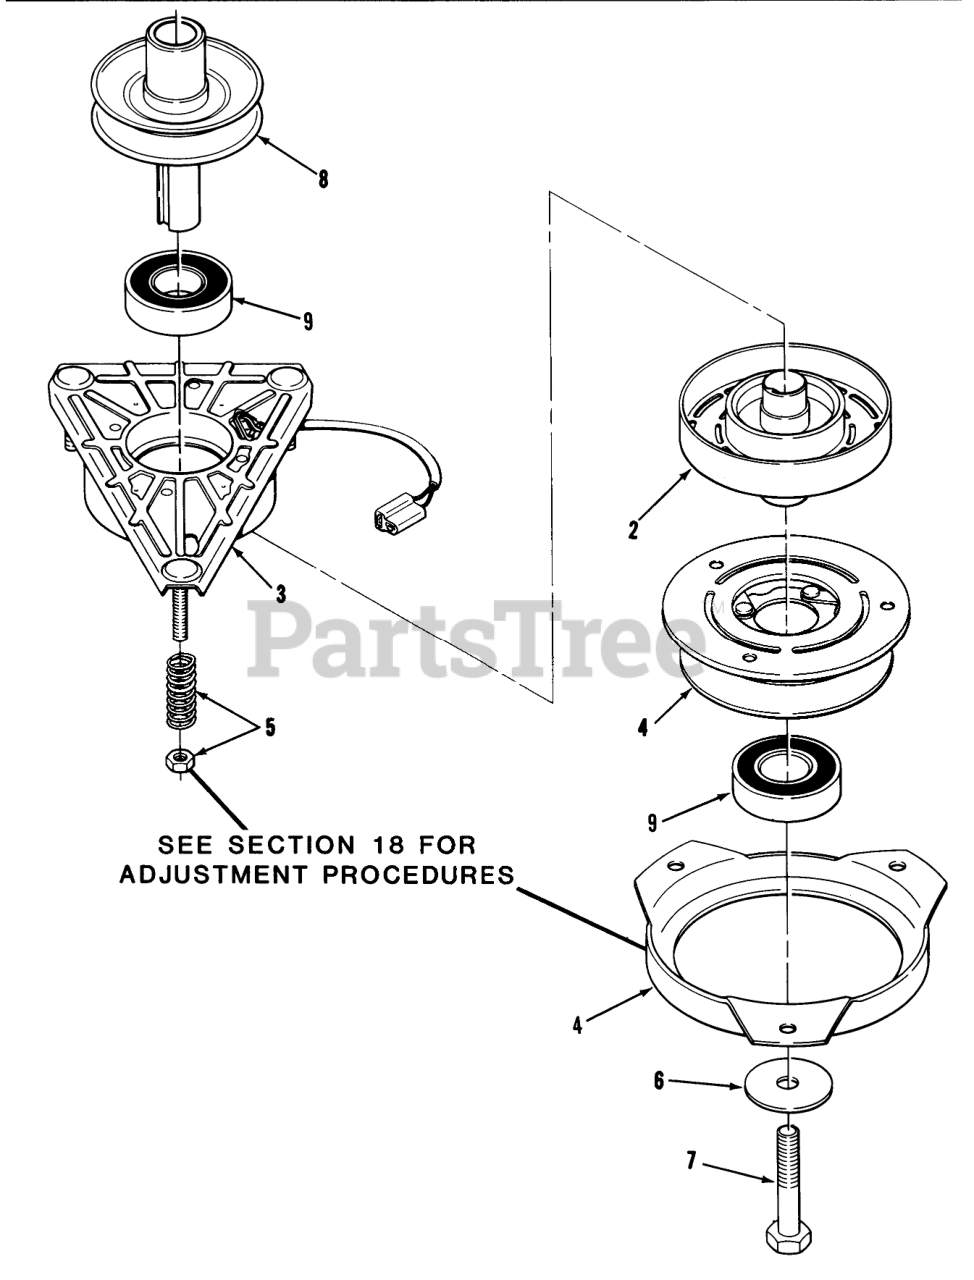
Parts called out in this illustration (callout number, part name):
1	Electric Clutch Assy (Includes items 2,3,4, & 5)
2	ASS'Y-ROTOR
3	Field Assy (Includes one of item 9)
4	Armature and pulley Assy (Includes one of item 9 and Brake Plate)
5	ACCESS SPRING & NUT
6	WASHER
7	Bolt
8	PULLEY-ENGINE
9	BEARING-ELEC CLUTCH
